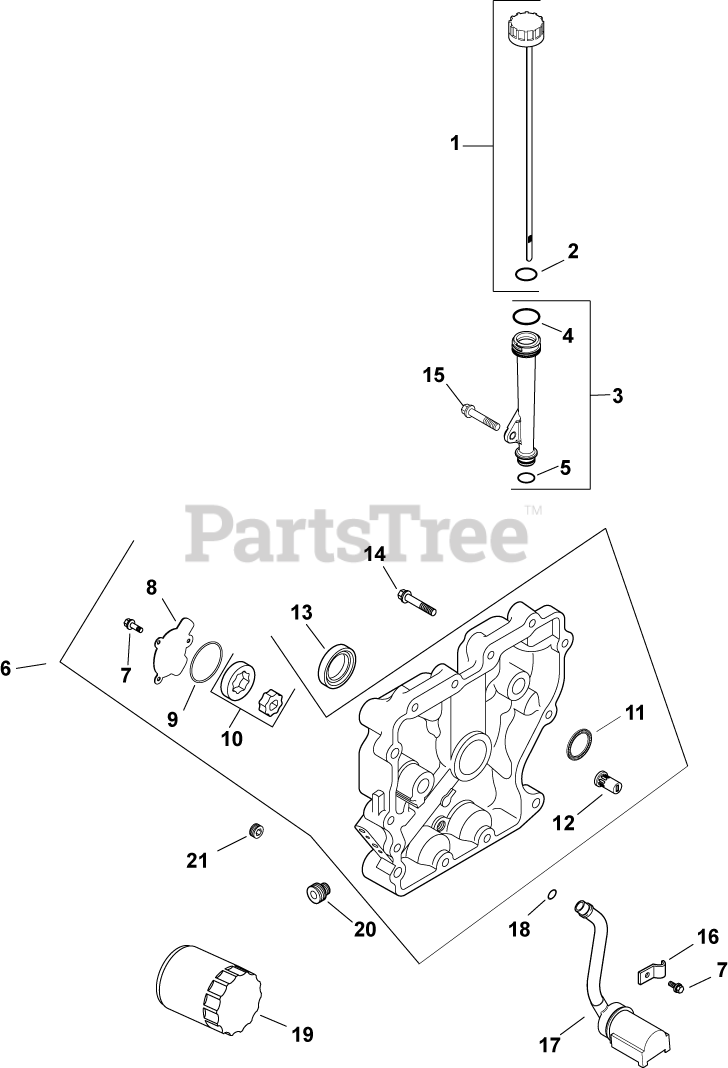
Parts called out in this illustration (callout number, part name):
1	KIT, OIL FILL CAP ASSEMBLY
2	O-RING, UPPER OIL FILL TUBE
3	KIT, OIL FILL TUBE - USE 12 755 113-S
4	O-RING, UPPER OIL FILL TUBE
6	PLATE, CLOSURE & BEARING
7	SCREW,FLG THD FRM M5X0.8X16-(#25086398S)
8	COVER, OIL PUMP
9	O-RING (1.78" DIA)
10	PUMP ASSEMBLY, OIL
11	BEARING, CRANKSHAFT
12	VALVE, OIL PRESSURE RELIEF
13	SEAL, OIL
14	SCREW, FLG M8X1.25X45
15	SCREW, FLG M8X1.25X50
17	KIT, OIL PICK-UP
18	O-RING (.5" DIA)
19	OIL FILTER
20	NIPPLE, OIL FILTER
21	PLUG, CTSK PIPE 1/8"
